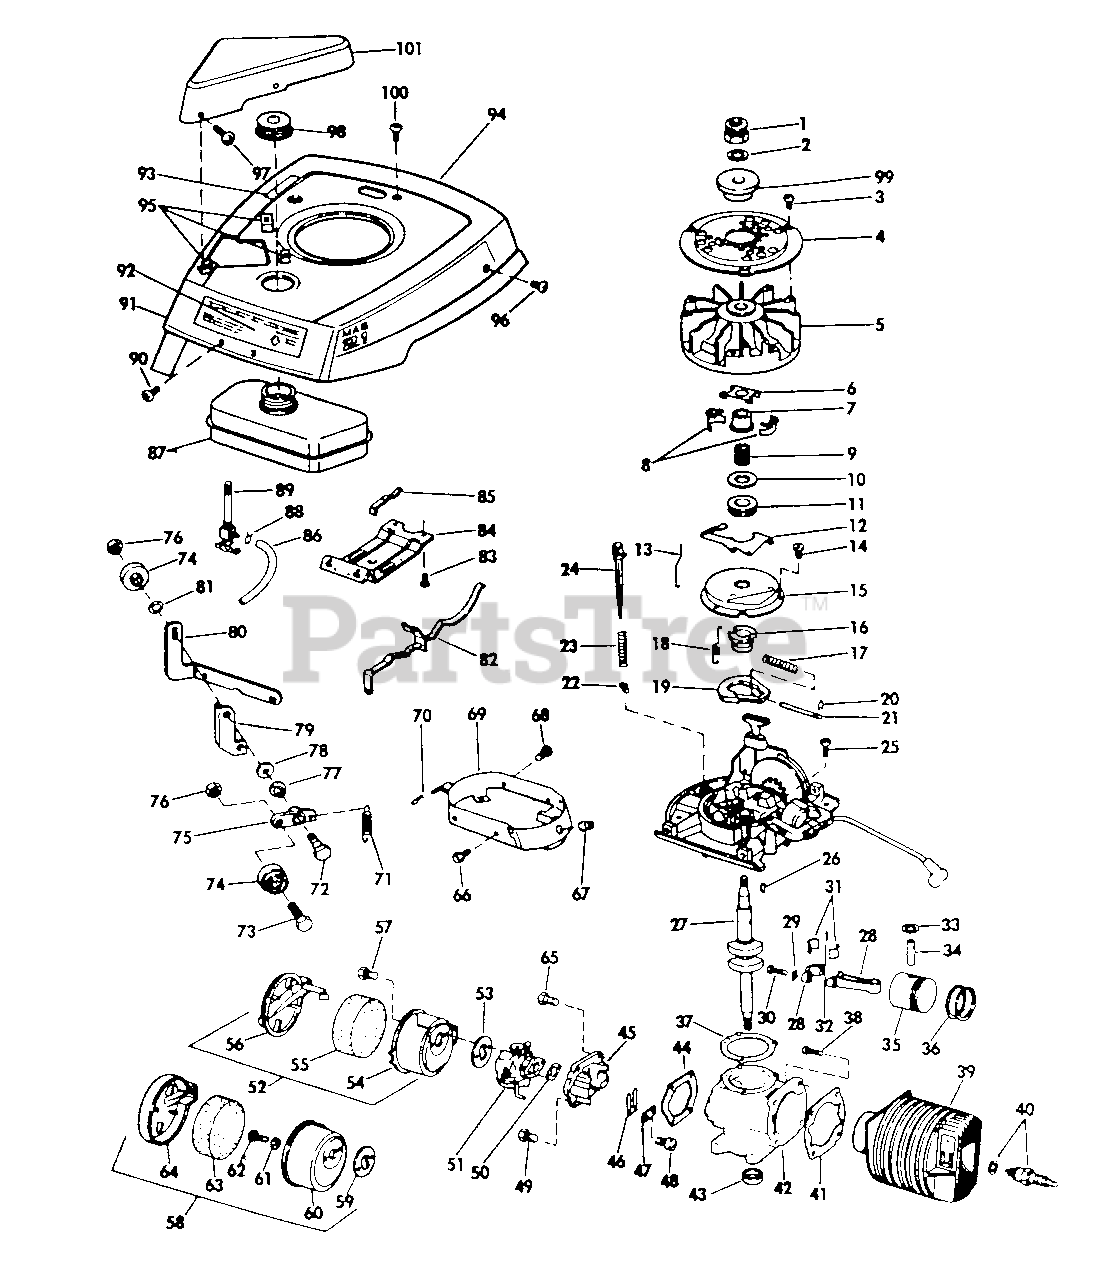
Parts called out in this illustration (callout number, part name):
2	Lockwasher-Flywheel
3	Screw-Thd. Cutting
5	Flywheel Assy.
6	Yoke-Governor
7	Collar-Governor
8	Weight-Governor
9	Spring-Governor
10	Thrust Washer
11	Collar-Thrust
12	Lever-Governor
13	Rod-Governor
14	Screw-Attachment Dust Cover
15	Dust Cover
16	Cam-Spark Advance
17	Spring-Spark Advance
18	Spring-Variable Speed
19	Flyweight-Spark Advance
20	Retainer-Spring
21	Pin-Spark Advance
22	Blade-Switch
23	Spring-Shut-Off Switch
24	Bar-Shut-Off & Primer
25	Screw-Arm. Plate to Crankcase
26	Key-Crankshaft
27	Crankshaft
28	Connecting Rod Assy.
29	Lockplate
31	Liners-Conn. Rod
32	Needle Bearing Set
33	Retaining Ring Wrist Pin
34	Wrist Pin
36	Ring Set (2 rings)
37	Gasket-Crankcase to Armature Plate .005 in.
37	Gasket Crankcase to Armature Plate .010 in.
38	Screw-Mach., Cylinder to Crankcase
39	Cylinder & Sleeve Assy.
40	Spark Plug & Gasket
41	Gasket-Cylinder to Crankcase
42	Crankcase & Seal Assy.
43	Oil Seal
44	Gasket-Reed Plate
45	Reed Plate Assy.
47	Plate-Back-Up
48	Screw-Machine
49	Screw-Hex Head, Reed Plate to Crkr.
50	Gasket-Carburetor
51	Carburetor Assy.
52	Air Filter Assy. (Metal)
53	Wick, Drain
54	Chamber-Filter
55	Element-Air Filter
56	Cover & Spring Assy.
57	Screw-Filter to Carburetor
58	Air Filter Assembly
60	Chamber (Plastic)
63	Element
64	Cap (Plastic)
65	Screw-Hex Head, Reed Plate to Crkc.
66	Screw-Baffle
67	Grommet-Cover Mtg.
69	Air Baffle Assy.
70	Nut-Cover Mounting
72	Shoulder Bolt
74	Idler Pulley & Bearing Assy.
76	Nut-Nylok
77	Grommet
79	Bracket-Spring Retainer
80	Bracket-Idler
81	Lockwasher
82	Control-Variable Speed
84	Bracket-Fuel Tank
85	Spring-Fuel Tank
86	Gas Line
87	Fuel Tank
88	Hose Clamp-Fuel Tank
89	Shut-Off Valve & Screen Assy.
90	Screw-Shroud Mtg.
91	Engine Cover Assy.
92	Decal-Instructions
93	Decal-On-Off Prime
94	Decal-Lawn-Boy
95	Fastener
96	Screw-Cover Mtg.
98	Cap-Gas Tank
99	Slinger
100	Screw-Cover to Starter Boss
101	Cover-Belt
